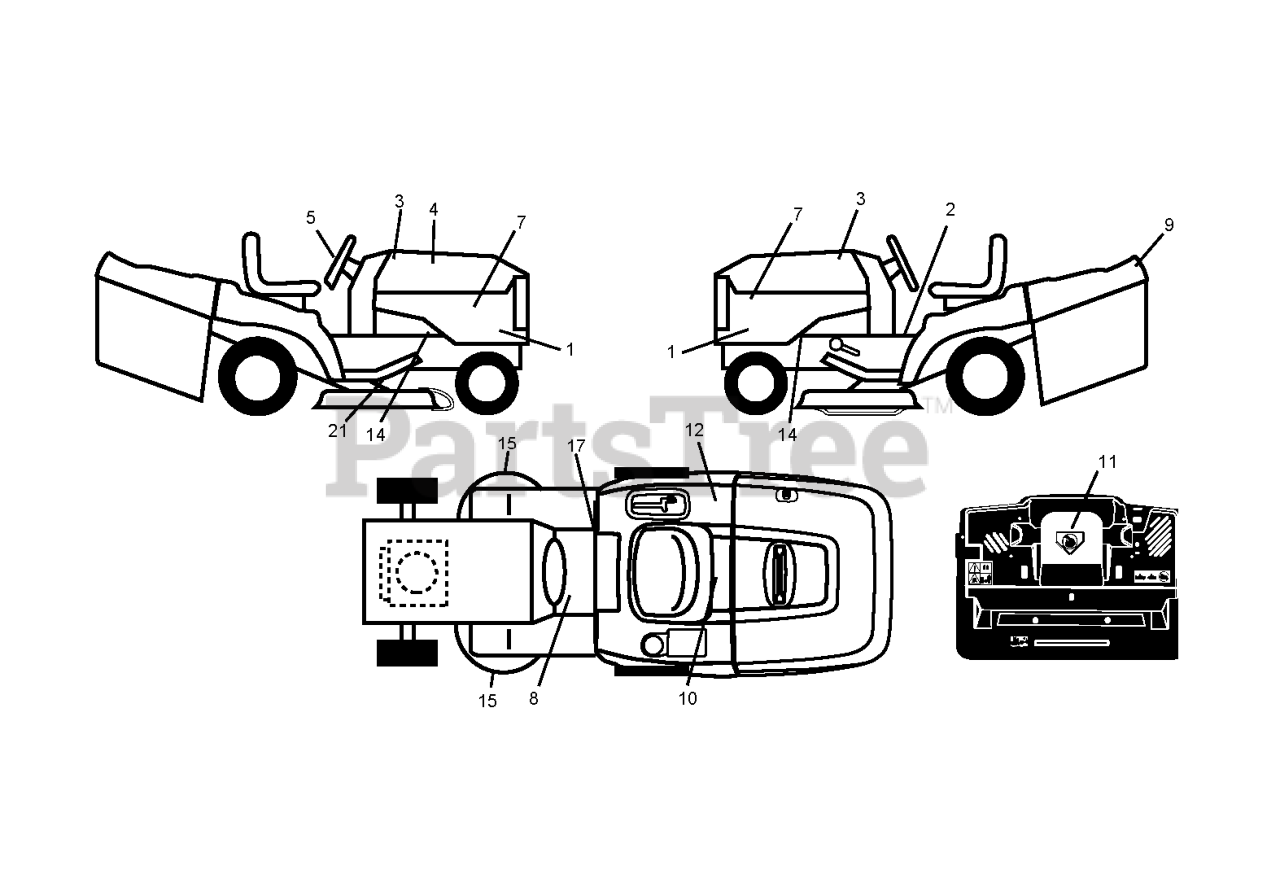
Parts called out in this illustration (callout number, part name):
2	LABEL
5	DECAL.STEERING.HUSQ.BLUE
7	DECAL.HOOD.HUSQVARNA.INTERNATI
8	DECAL
10	DECAL BTRY SYMBOLS
11	DECAL.INTERNATIONL.CUTFINGER
12	Decal, Fender 100 DB/CE
17	DECAL PARK BRAKE
